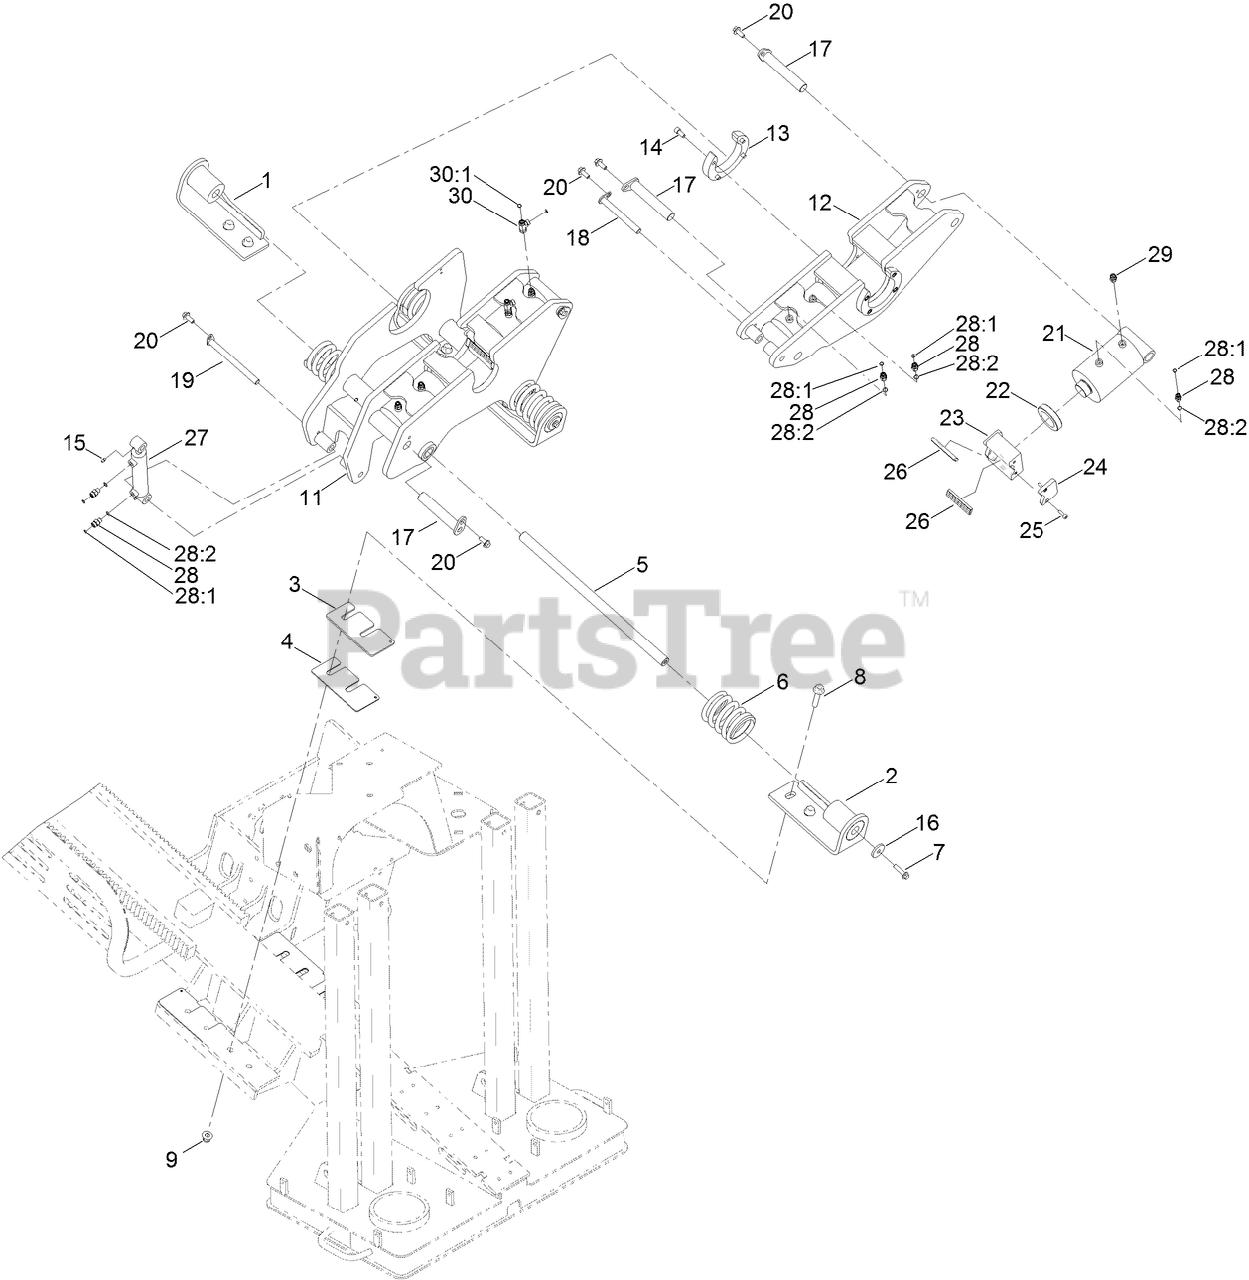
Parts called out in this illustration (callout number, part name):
1	BRACKET-MOUNTING, WRENCH
2	BRACKET-MOUNTING, WRENCH
3	SHIM-PLATE, WRENCH
4	SHIM-PLATE, WRENCH
5	PIN-WRENCH
6	SPRING-COMPRESSION
7	SCREW-HHF
8	SCREW-FLANGE
9	NUT-HHF
11	WRENCH-FRONT
12	REAR-WRENCH
13	GUIDE-WRENCH
14	SCREW-HSH
15	FITTING-GREASE
16	WASHER-FLAT
17	PIN-W/FLAG
18	PIN-RETAINNG
19	PIN-RETAINING
20	SCREW-HHF
21	HYD CYLINDER ASM
22	BUSHING-CYLINDER
23	HOLDER-DIE, WRENCH
24	RETAINER-DIE, WRENCH
25	SCREW-HSH
26	TONG-DIE
27	HYD CYLINDER ASM
28	FITTING-STRAIGHT
28:1	O-RING
28:2	O-RING
29	FITTING-ORIFICE
30	FITTING-TEE, SWIVEL NUT
30:1	O-RING
